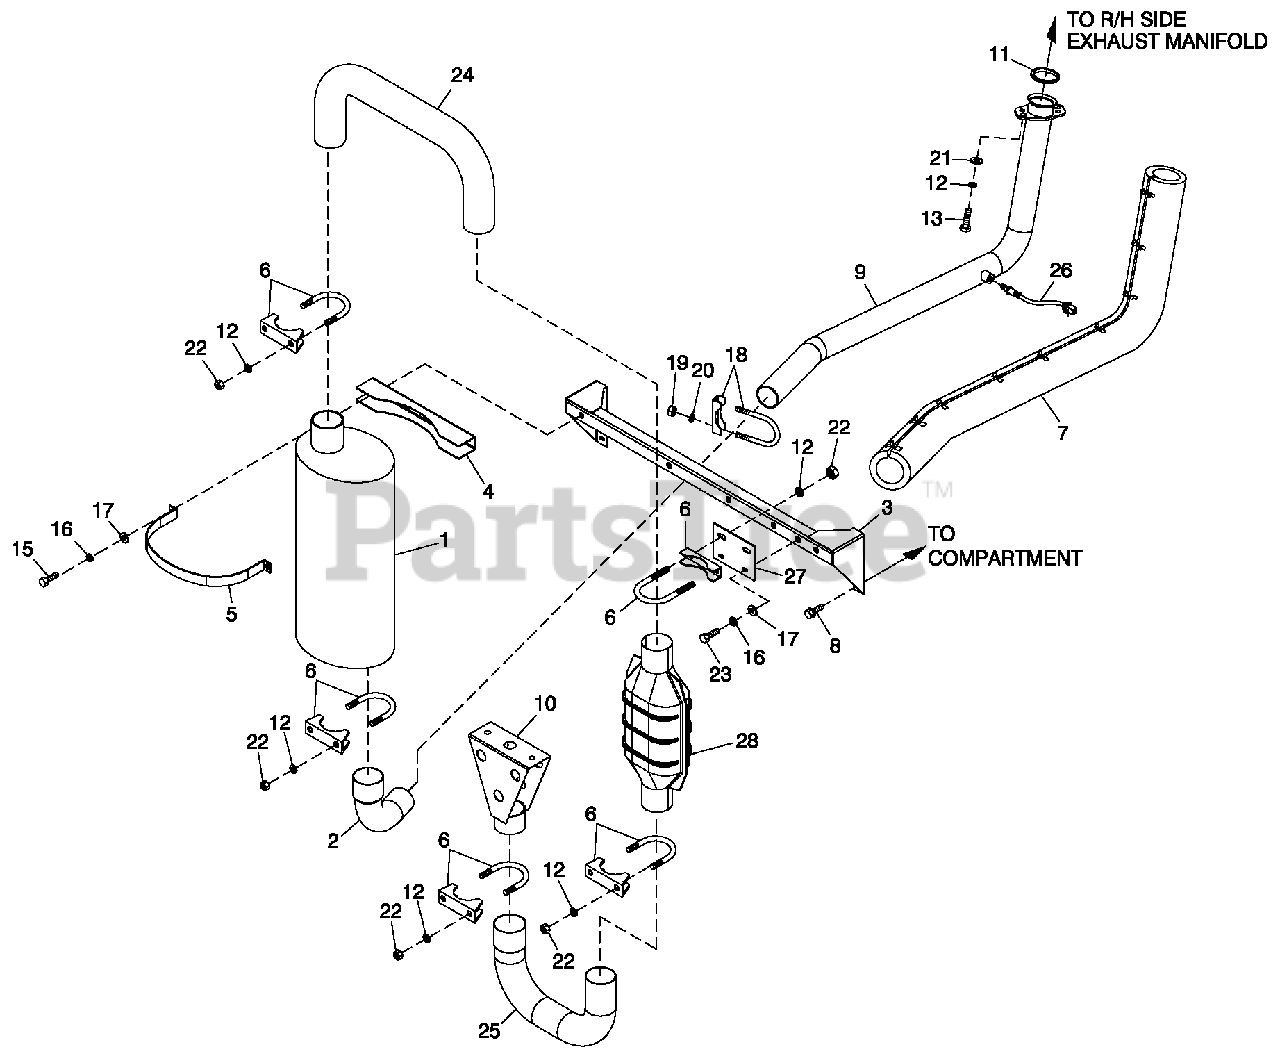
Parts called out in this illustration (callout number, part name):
1	ROTOR-2390-45KD1 CPL
2	ROTOR-2390-35KD1 CPL
3	ROTOR-2390-45KD1 CPL (G2)
4	ROTOR-2390-35KD1 CPL (G2)
5	ROTOR 25KW 3PH DIRECT 390 1800
6	ROTOR 25KW 1PH DIRECT 390 1800
7	EXHAUST BLAN KET 988MM
8	SCREW THF M6-1 X 16 N WA Z/JS
9	PIPE EXHAUST G2 EMISSIONS
10	STATOR-390 45K 2P 1PH DIRECT
11	STATOR-2390-35AD1 CPL
12	STATOR-2390-35KD1 CPL
13	STATOR-2390-35GD1 CPL
15	STATOR-2309-45KW 2P 3PH 208V
16	STATOR-2309-45-KD1 CPL
17	WASHER FLAT 1/4-M6 ZINC
18	BOLT U 5/16-18X2.25
19	NUT HEX 5/16-18 STEEL
20	WASHER LOC K M8 SS
21	WASHER FLAT 3/8 SS
22	NUT HEX 3/8-16 STEEL
23	SCREW HHC M6-1.0X 16 G8.8
24	PIPE, EXHAUST CROSSOVER EMSSM
25	PIPE, EXHAUST MUFFLER OUT
26	SENSOR OXYGEN
27	PLATE, CATALYST MOUNTING
28	CATALYST AF-RATIO
